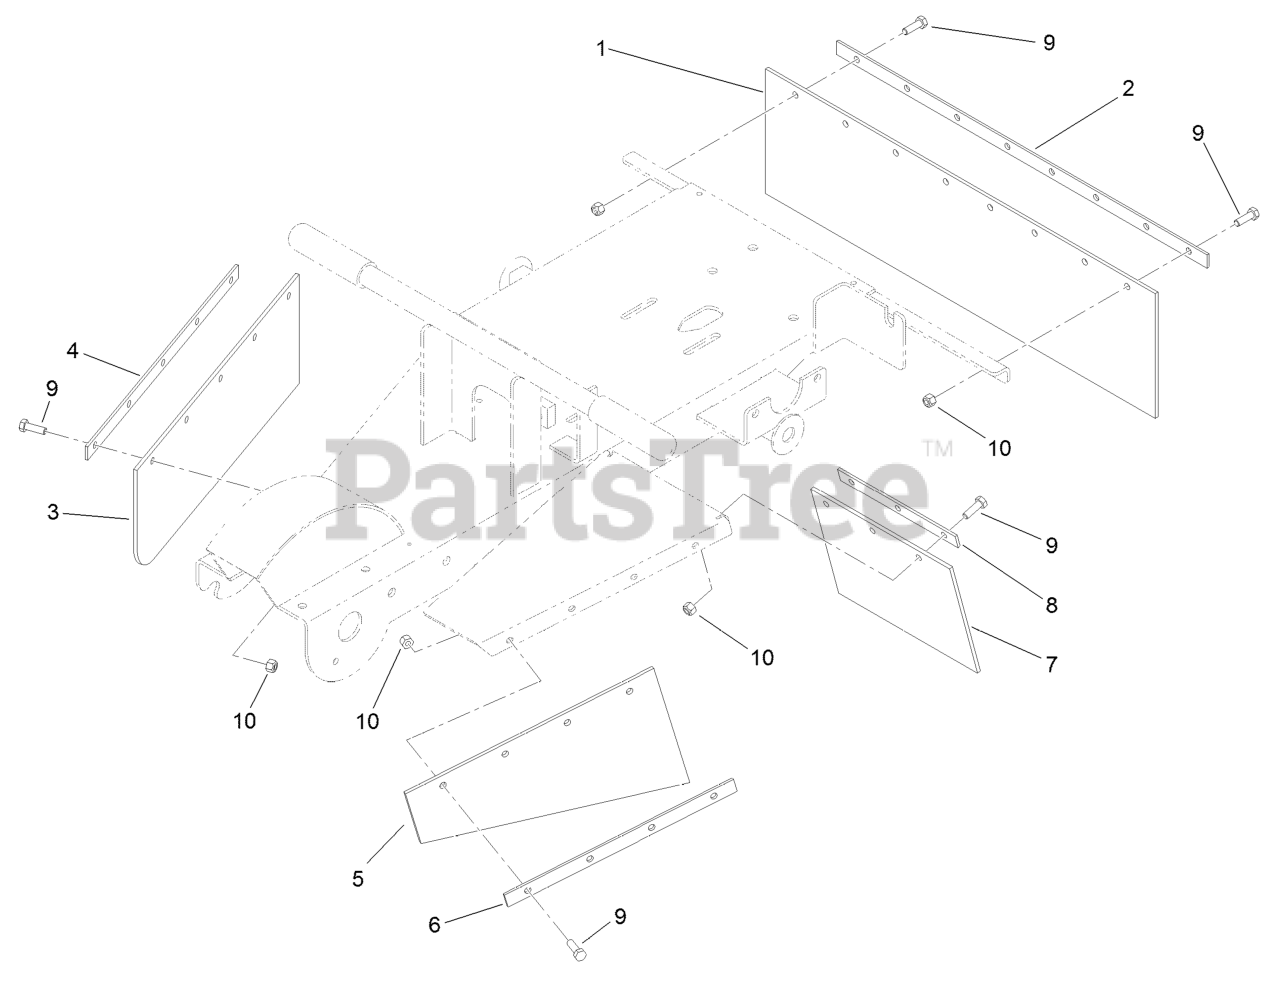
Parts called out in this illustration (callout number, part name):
1	FLAP-REAR
2	PLATE-MOUNTING, FLAP
3	FLAP-RH
4	BRACKET-SUPPORT, FLAP (RH
5	FLAP-LH
6	BRACKET-SUPPORT, FLAP (LH
7	FLAP-SMALL
8	BRACKET-SUPPORT, FLAP
9	SCREW-HH
10	NUT-LOCK, NI
